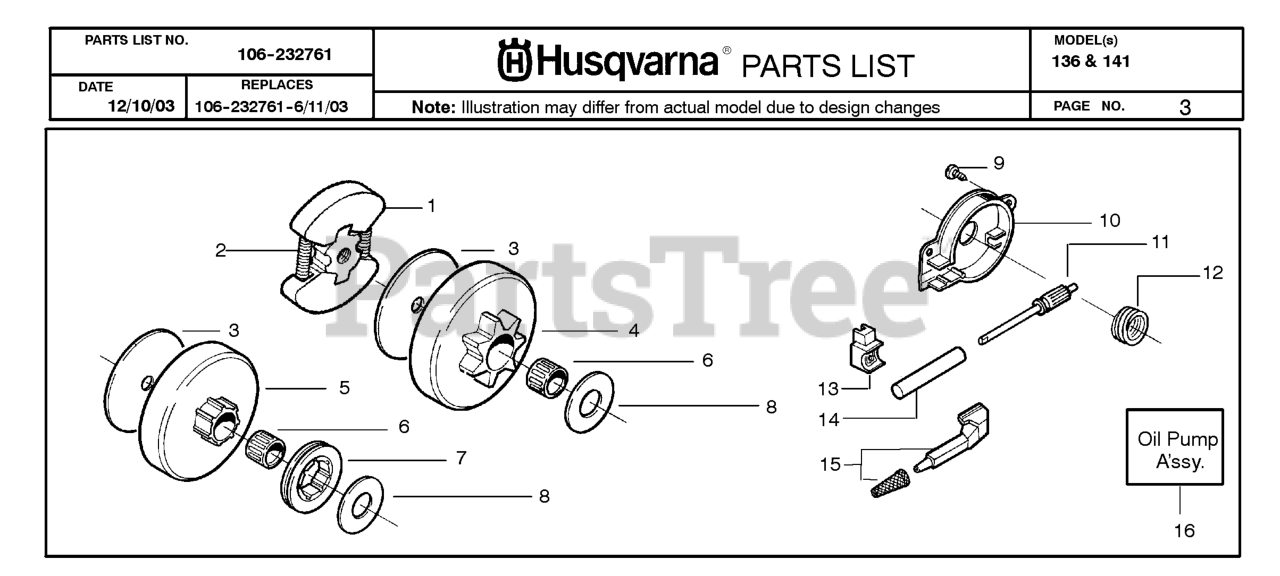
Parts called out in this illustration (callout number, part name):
1	CLUTCH ASSEMBLY
2	CLUTCH SPRING 36/41
3	FRICTION DISC,CLUTCH 36/41
4	CLUTCH DRUM ASSY
5	CLUTCH DRUM 325 X 7T
6	NEEDLE BEARINGS 36/41
7	RIM .325 7T 36/41
8	THRUST WASHER
10	OIL PUMP HOUSING
11	PLUNGER & GEAR ASSEMBLY
12	OILER GEAR 36/41
13	PRESSURE SEAL,OILER 36/41
14	OIL PUMP BARREL
15	OIL PICKUP
16	OILER ASS'Y 36/41
